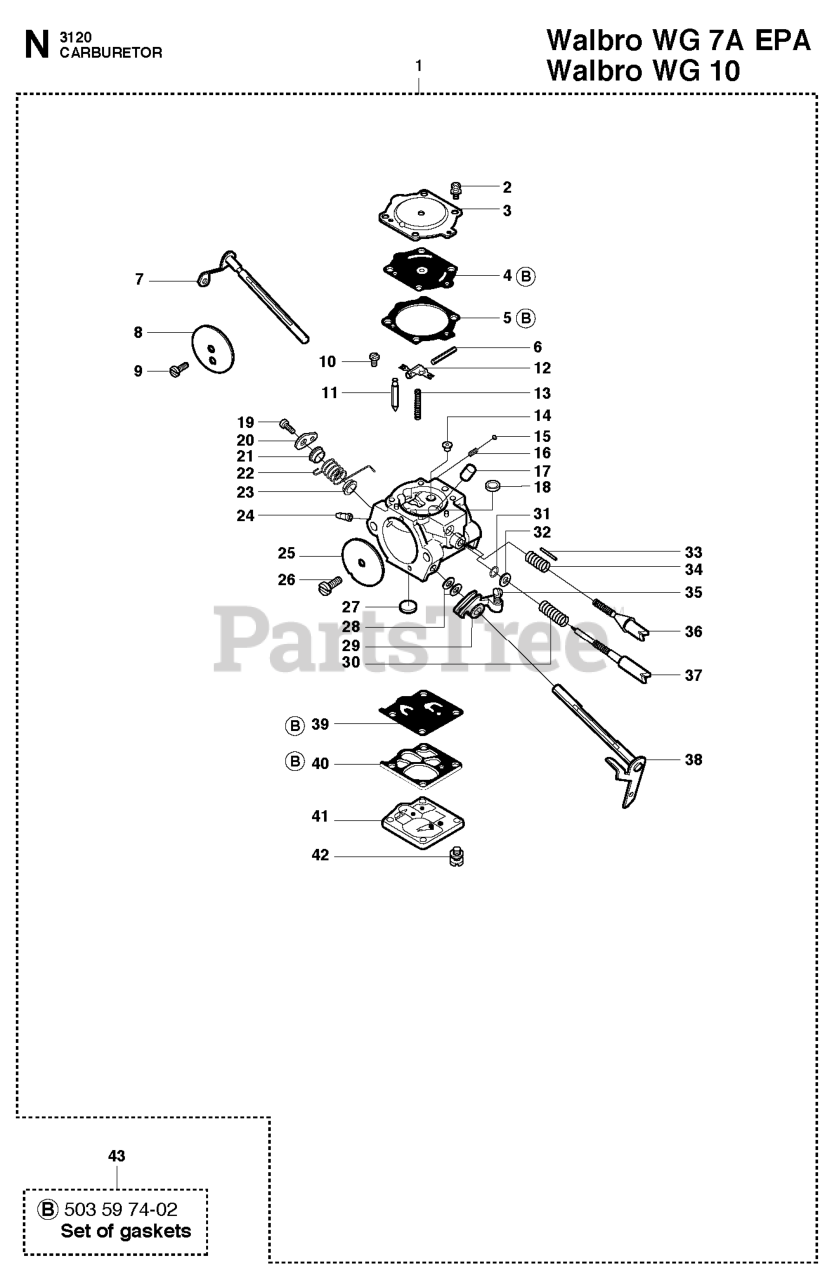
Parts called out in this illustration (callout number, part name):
1	CARBURETOR
1	CARBURETOR WG7 EPA
2	RP SCREW W/ WASHER
3	COVER DIAPH
4	METERING DIAPHRAGM GSKT
7	CHOKE SHAFT
8	CHOKE SHUTTER
9	SCREW SHUTTERS
11	VALVE INLET NEEDLE
13	LEVER SPRING
14	NOZZLE ASSY CH.VALVE
14	MAIN JET
18	WELCH PLUG
22	SPRING,THROTTLE RETURN
24	FUEL NIPPLE-CARB
25	SHUTTER-THROTTLE
26	SCREW SHUTTERS
27	FUEL INLET SCREEN
30	PRESSURE SPRING
33	ADJ NEEDLE-LO,CARB
34	SPRING-MIX NEEDLE
36	ADJ SCREW-LO,CARB
37	HI-NEEDLE,CARB
38	THROTTLE SHAFT
39	DIAPHRAGM/PUMP
42	SCREW W/ WASHER
43	DIAPHRAM SET
